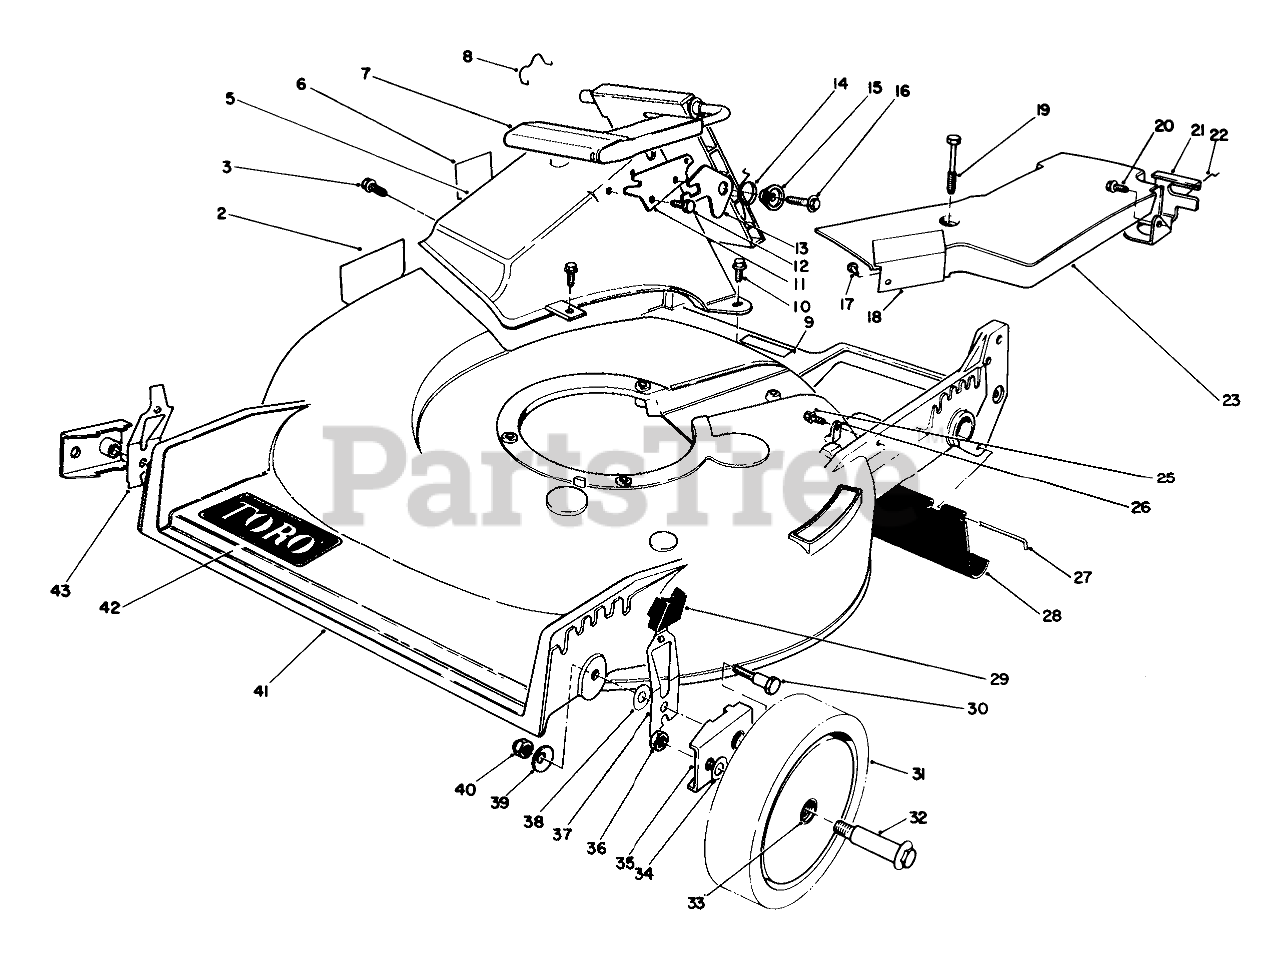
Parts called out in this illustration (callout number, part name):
2	DECAL-DANGER
3	SCREW AND WASHER ASM
5	Tunnel-Discharge (Incl. Ref. #6)
6	DECAL - DANGER
7	Discharge Door Assembly
8	DOOR RET SPRING
9	Decal
10	SCREW-HWH
11	DOOR LATCH PLATE
12	SCREW-PLASTITE
13	Latch-Door
14	TORSION SPRING
15	DOOR SPACER
16	SCREW-HWH
17	RIVET-HEAD, FLAT
18	HEAT SHIELD
19	SCREW-HHFTF
20	SCREW-HWHTF
21	Bracket-Traction Adj.
22	RETAINER-CABLE
23	Belt Cover Assembly (Incl. Ref. #17 & 18)
25	SCREW
26	CLAMP-CABLE
27	ROD-SHIELD
28	SHIELD-TRAILING
29	KNOB-ARM
30	PIVOT SCREW
31	Wheel & Tire Assembly (Incl. Ref. #33)
32	BOLT-WHEEL
33	BUSHING
34	WASHER
35	HP PIVOT ARM ASM
36	Nut
37	L. HP SPRING ARM ASM
38	WASHER-PIVOT
39	WASHER-BELLEVILLE
40	NUT-LOCK, NI
41	Housing
42	DECAL
43	R HP SPRING ARM ASM
